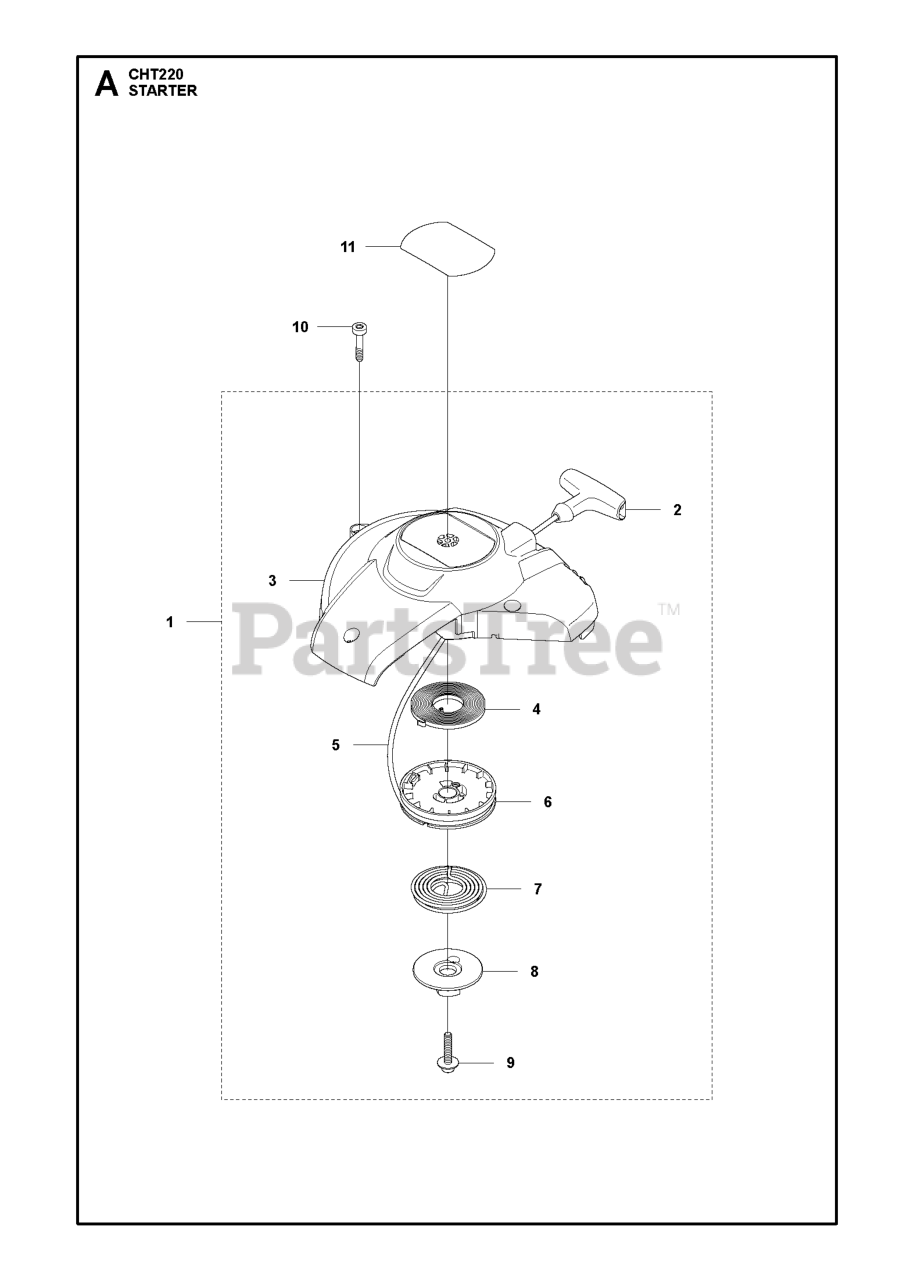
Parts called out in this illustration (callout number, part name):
1	STARTER ASSY
2	STARTER HANDLE
3	STARTER HOUSING
5	STARTER CORD
6	STARTER PULLEY
10	SCREW CITXSCMO M5X25
11	DECAL STARTER
